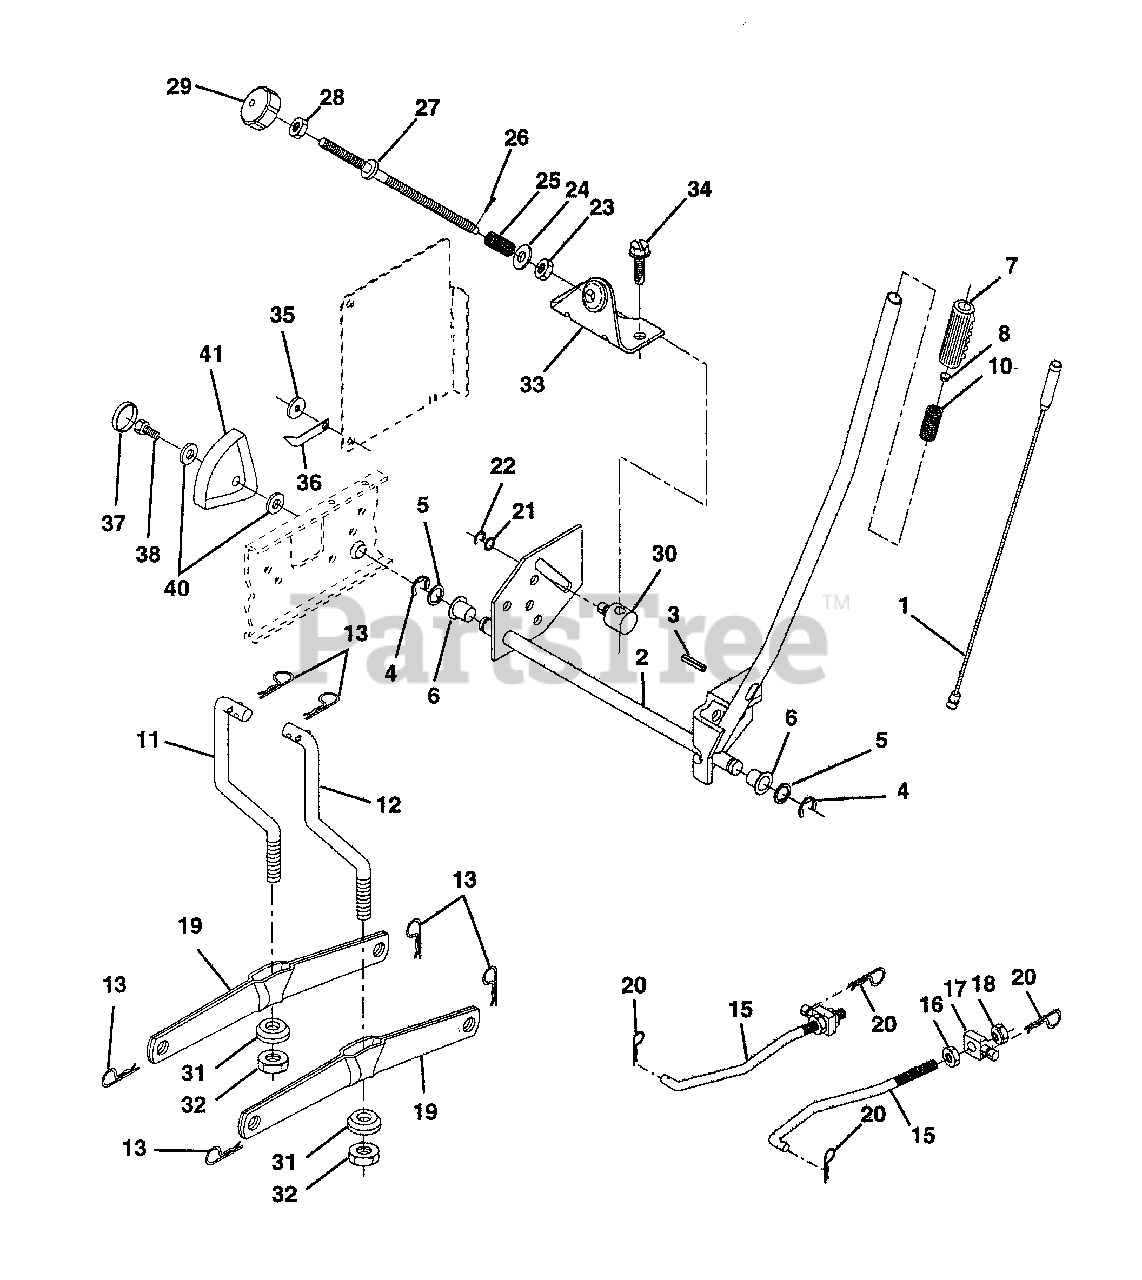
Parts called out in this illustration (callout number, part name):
1	Wire Asm Inner W/plunger 17.32
2	Shaft Asm Lift RH w/Inf
3	Pin Groove 1 500 Zinc
4	E Ring #5133-62
5	Washer 21/32 X 1 X 21 Ga
6	Bearing Nylon Blk 629 Id
7	Grip Handle Fluted Blk
8	Button Plunger Black
10	Spring Cprsn 3 750 Oiled
11	Link Lift LH Fixed Length
12	Link Lift RH Fixed Length
13	Retainer Spring
15	Link Front
16	Nut Jam Hex 1 /2-13 Unc
17	Trunnion Blk Zinc
18	Nut Lock W/wsh 1/2-13unc
19	Arm Suspension Rear
20	Retainer Spring
21	Washer 15/32 X 3/4 X 16 Ga
22	Ring Klip #t5304-37
23	Nut Special
24	Washer 13/32 X 5/8 X 16 Ga
25	Spring 2-1/8"
26	Pin Cotter 3/32 X 1/2
27	Rod Adj Lift Zinc 7.49 Wrk Lg
28	Nut Hex Jam 3/8-16 Unc
29	Knob Inf 3/8-16 Unc Blk W/sym
30	Trunnion Dp Stop Dbl Thds PLT
31	Bearing Pvt Lift Spherical
32	Nut Nylock 3/8 - 24
33	Bracket, Stop Inf. Hgt.
34	Screw THDROL 3/8-16 x 1/2 TY-TT
35	Washer Nylon .44 x .75 x .032
36	Pointer Pnt Height ind .505
37	Plug Hole Blk 1.485/1.515 Dia.
38	Screw Thdrol 5/16-18 x 3/4
40	Washer 11/32 x 1-1/2 10 Ga.
41	Scale Ind. Height Blk.
